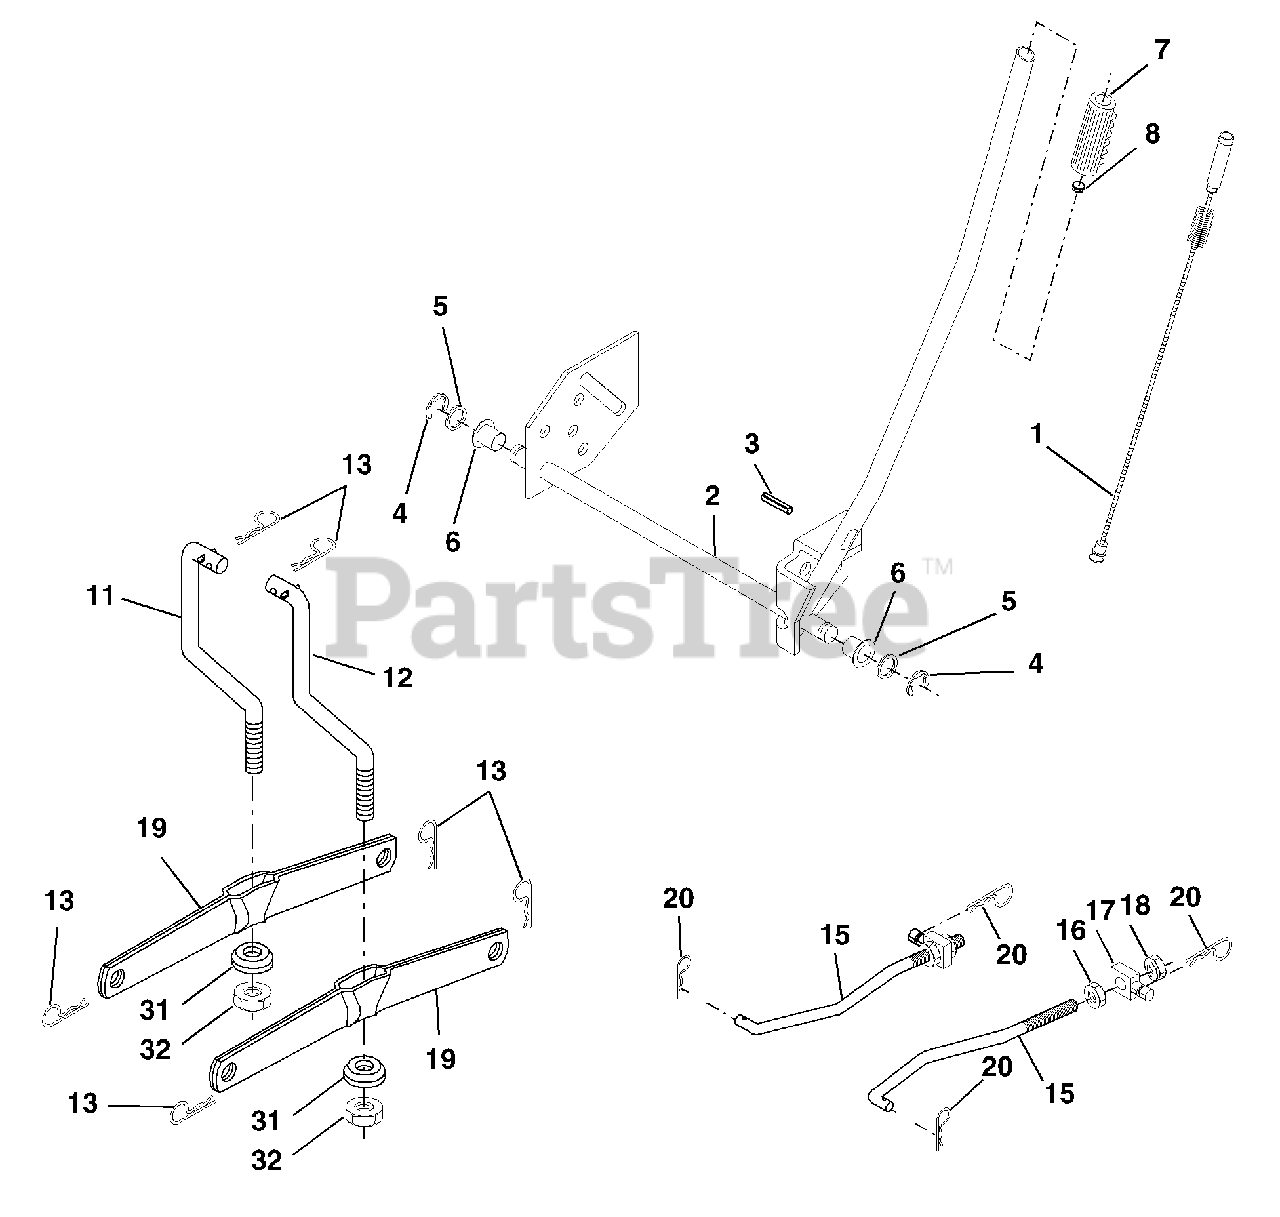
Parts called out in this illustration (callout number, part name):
1	Wire Asm Inner W/plunger
2	Shaft Asm Lift
3	Pin Groove 1 500 Zinc
4	E Ring #5133-62
5	Washer Pltd 21/32 X 1 X 21ga
6	Bearing Nylon Blk 629 Id
7	Grip Handle Fluted Blk
8	Button Plunger Red
11	Link Lift LH
12	Link Lift RH
13	Retainer Spring
15	Link Front
16	Nut Jam Hex 1/2-13 Unc
17	Trunnion Blk Zinc
18	Nut Lock w/Wsh 1/2-13 UNC
19	Arm Suspension Rear
20	Retainer Spring Zinc
31	Bearing Pvt Lift
32	Nut Crownlock 3/8-24
